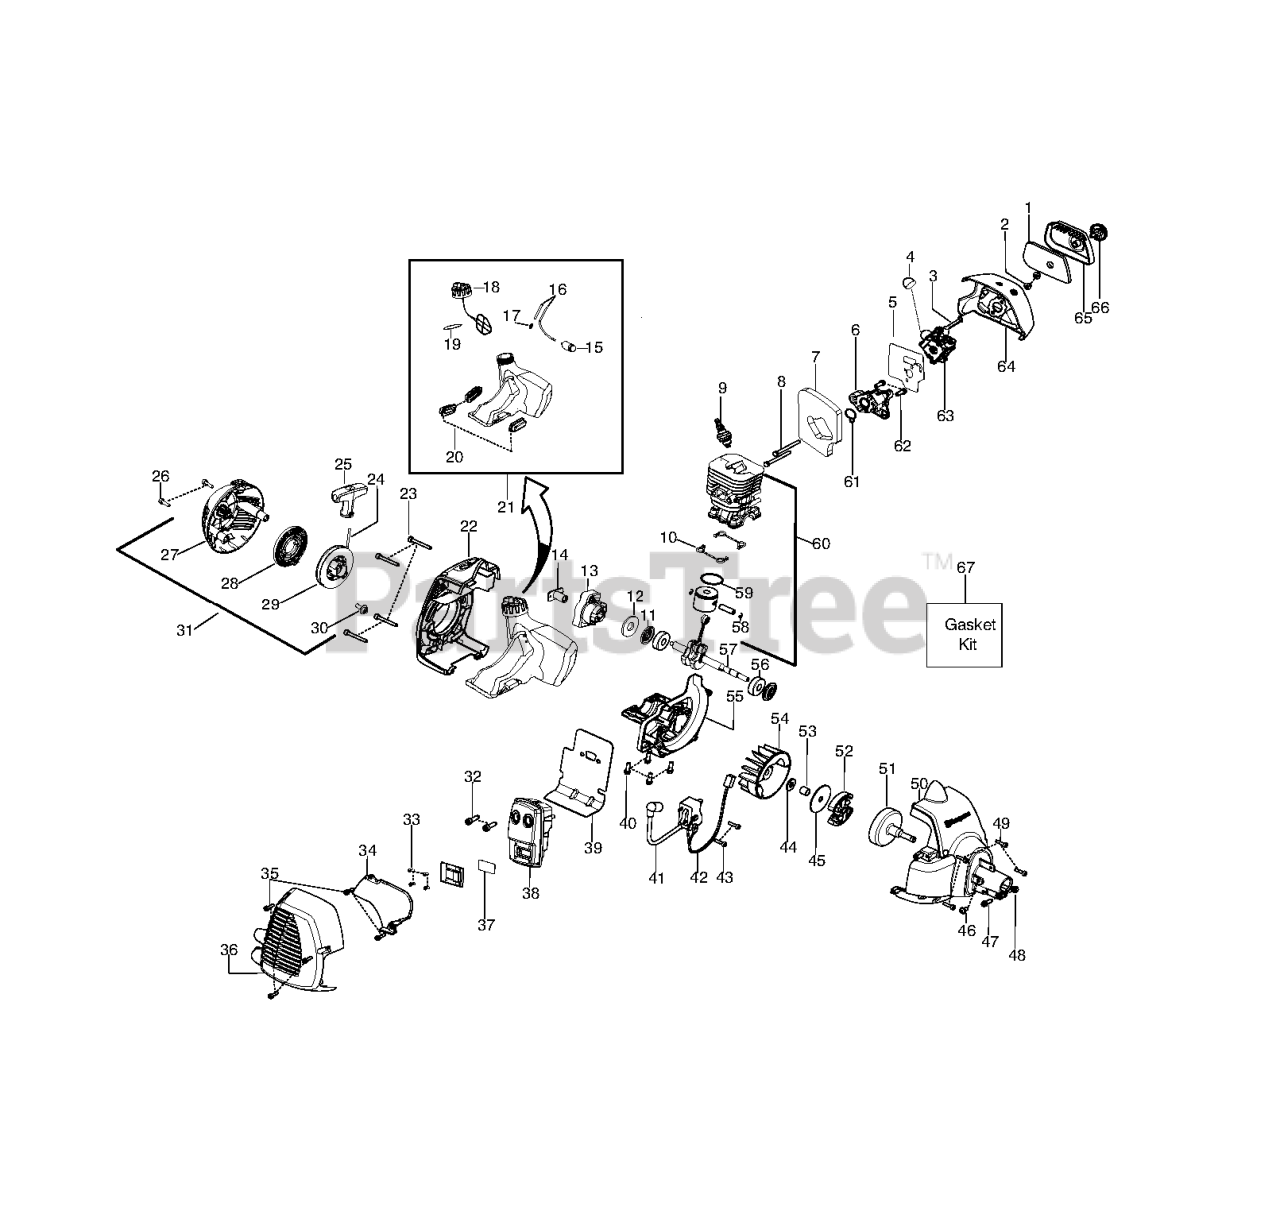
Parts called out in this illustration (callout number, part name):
1	DECK SVCX1 38/94 192556X431
2	RP BOLT 5/16-18 X3/4 ZN/YEL GR
3	BRKT ASM SWAY BAR
4	BRACKET DECK SWAY BAR 38"/42"
5	RETAINER-SPRNG RB
6	BAR SWAY DECK
7	NUT.71038.31-18.HEX.NYLOCK
8	BOLT.WASHER.ASM.7/16-2
11	BLADE 38" PREMIUM
13	SHAFT.ASM.MDRL.N/GREASE.38
14	RP.HOUSING.MANDREL.4PT.
18	BOLT
19	BOLT SHD 5/16-18
20	BAFFLE.VORTEX.FRONT.38"
21	LOCKNUT
23	BRKT.DEFLECTOR.38"2005+
24	CAP-SLEEVE LT
25	SPRING.TORSION.DEFLECT
26	NUT PUSH M
27	SHIELD ASM.DFLCTR MWR.38-7"BLK
29	ROD.HINGE
30	SCREW, WASHER HEAD
31	WASHER.SPACER.MANDREL
32	PULLEY MANDREL
33	NUT.FLANGE.LOCK.TOP
36	FLAT IDLER PULLEY
37	PULLEY.IDLER.FLAT.UNPLATED
45	RETAINER M
46	SCREW.1/4-20X5/8
55	IDLER ARM
56	SPACER.RETAINER.MOWER
67	KNOB T (3/8 HOLE)
68	V-BELT.MOWER.38"2005+
72	SPRING.BRAKE.RETURN.38"
89	WASHER
107	SPACER.IDLER.ARM
108	STIFFENER.IDLER.ARM
122	LINK.BRAKE.38"LEFT.2007
123	LINK.BRAKE.38"RIGHT
144	KEEPER BELT
148	IDLER RETURN SPRING
149	SPRING.RETAINER.YELLOW.ZINC
150	WASHER LT
152	CABLE.CLUTCH.38".SERVICE
158	SCREW
185	HEAD ASM. CABLE CLUTCH
186	SCREW.HXWSH.3/8
187	KEEPER BELT
188	BOLT, CARRIAGE IDLER
189	STAND, BRAKE
190	ARM, BRAKE
191	BRAKE.SPACER.38".DECK
193	KEEPER BELT RH MANDREL
194	GUARD BRAKE
195	WASHER 12/32X2X10GA
205	SCREW
206	WASHER
208	SCREW 3/8-16X1/2
214	BOLT/WASHER ASM 5/16-18
